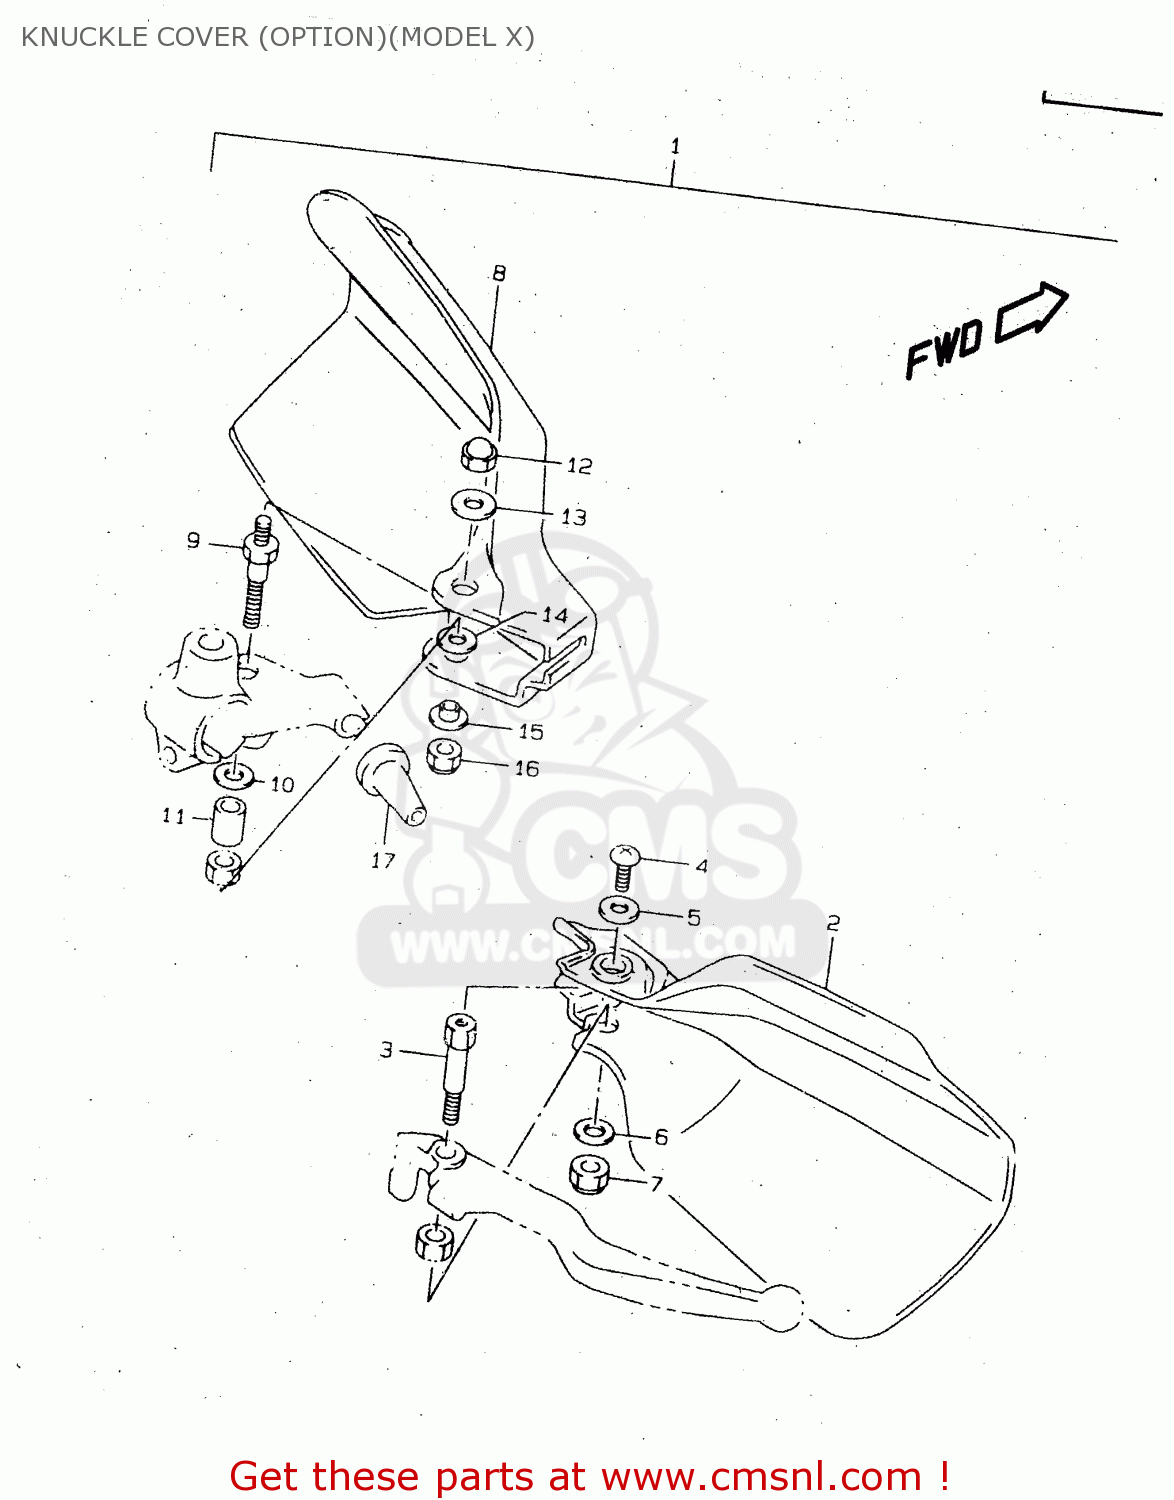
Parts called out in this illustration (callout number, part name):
1	COVER SET,KNUCKLE
2	COVER,KNUCKLE,RIGHT
3	BOLT,BRAKE LEVER PIVOT
4	SCREW
5	WASHER(5.5X16X1.2)
6	WASHER(6.5X16X1.6)
7	NUT 6MM
8	COVER,KNUCKLE,LEFT
9	BOLT,CLUTCH LEVER PIVOT
10	WASHER,LEVER SET
11	SPACER,LEVER SET
12	NUT
13	WASHER(6.5X20X1.6)
14	WASHER(6.5X16X1.2)
15	WASHER
16	NUT 6MM
17	BOOT,CLUTCH CABLE
